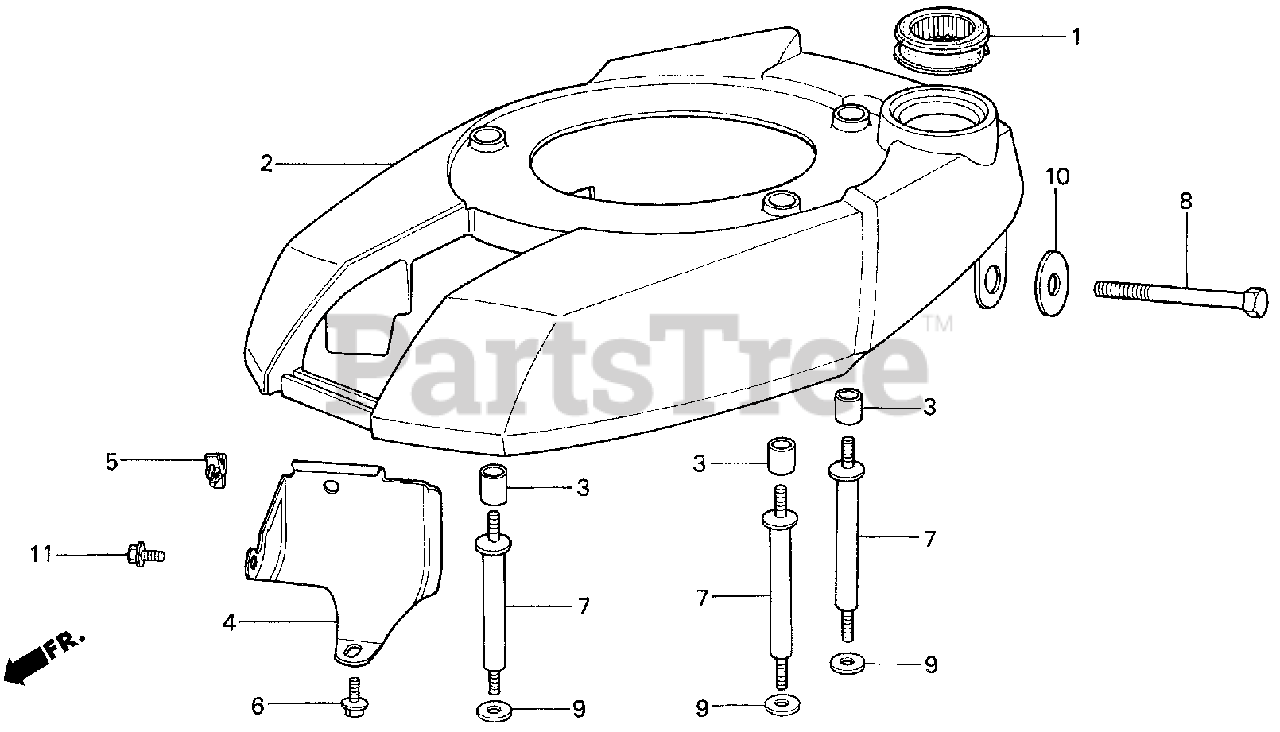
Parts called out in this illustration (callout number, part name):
1	RUBBER A, TANK MOUNTING (NOT AVAILABLE)
2	COVER, FAN (NOT AVAILABLE)
3	COLLAR, RECOIL STARTER
5	CLIP, IGNITION WIRE (8MM)
6	BOLT, FLANGE (6X12) (CT200)
7	BOLT, SPECIAL STUD
8	BOLT, FUEL TANK (NOT AVAILABLE)
9	WASHER (6MM)
9	WASHER, PLAIN (5MM)
10	WASHER, TANK MOUNTING
11	BOLT, FLANGE (6X12)
